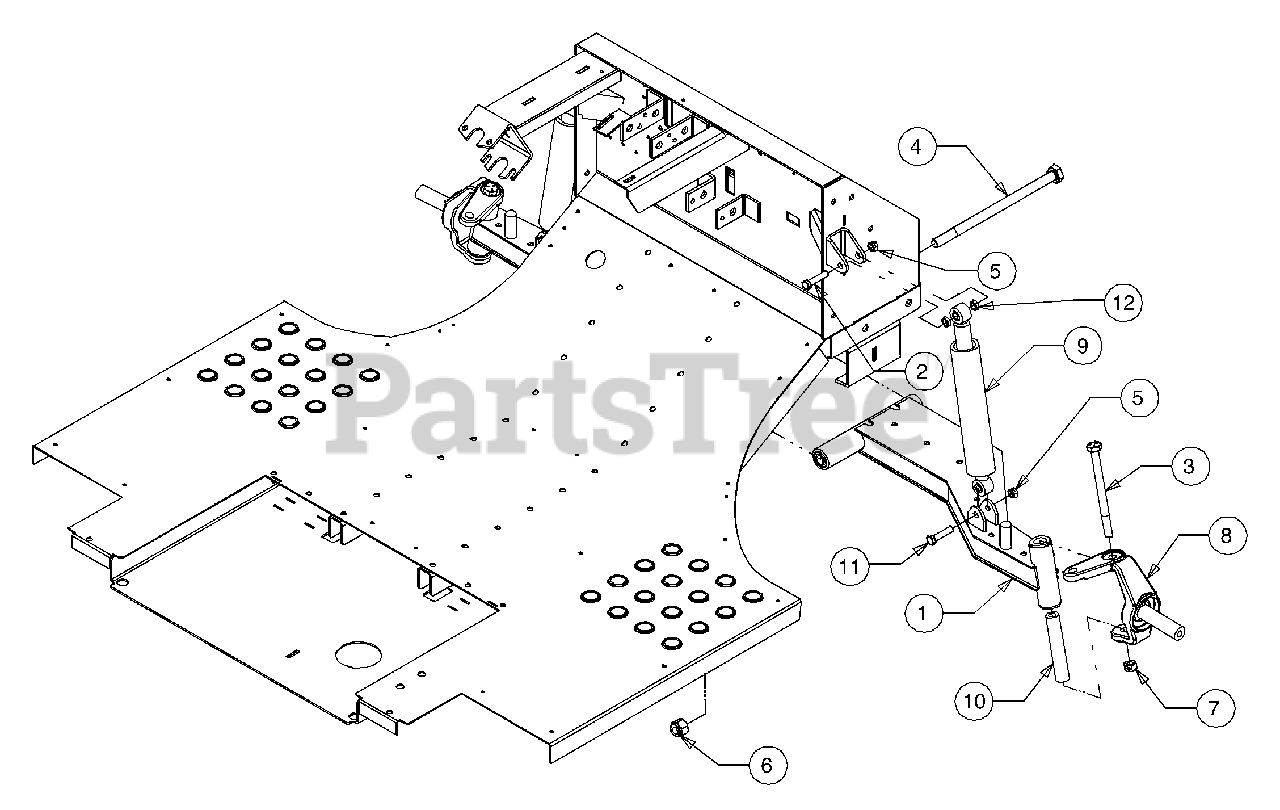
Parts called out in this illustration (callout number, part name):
1	Axle Assembly, Right-front
2	Hex Screw, M10-1.25 x 65mm
3	Hex Screw, 1/2-13 x 6.50, Gr5
4	Hex Screw, 5/8-11 x 11, Gr5
5	Nut, Hex Lock, Nylon, M10 -1.25
6	Nut, Hex Lock, Nylon, 5/8-11, Gr5
7	Nut, Hex Lock, 1/2-13
8	Steering Control Knuckle, RH
9	Shock Absorber, 2.88 Stroke
10	Tube, .875 x .50 x 4.75
11	Hex Screw, M10-1.25 x 50mm
12	Spacer, Shock
